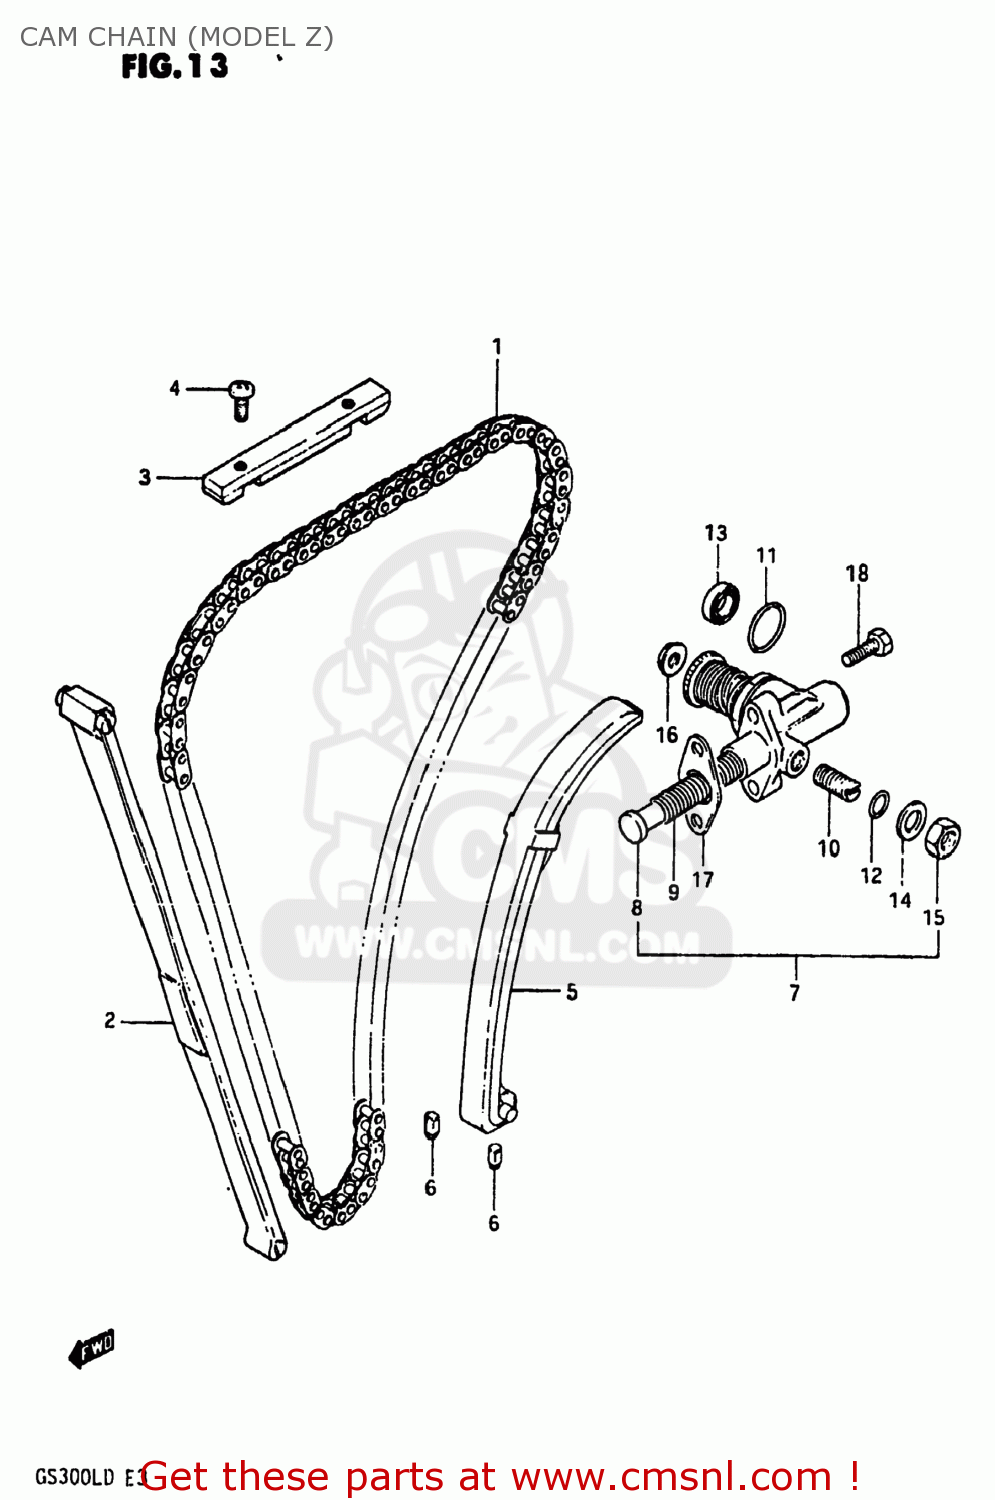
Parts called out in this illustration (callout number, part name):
1	CHAIN,CAMSHAFT DRIVE
2	GUIDE,CAM CHAIN NO.1
3	GUIDE,CAM CHAIN NO.3
4	SCREW
5	TENSIONER,CAM CHAIN
6	CUSHION,CAM CHAIN TENSIONER
7	ADJUSTER ASSEMBLY,TENSIONER
8	ROD,PUSH
9	SPRING
10	SCREW
11	O RING(D:2.4,ID:20.8)
12	O RING(D:1.9,ID:5.7)
13	SEAL,OIL(10X16X4)
14	WASHER
15	NUT
16	NUT
17	GASKET,TENSIONER ADJUSTER (MCA)
18	SCREW (6X25)
